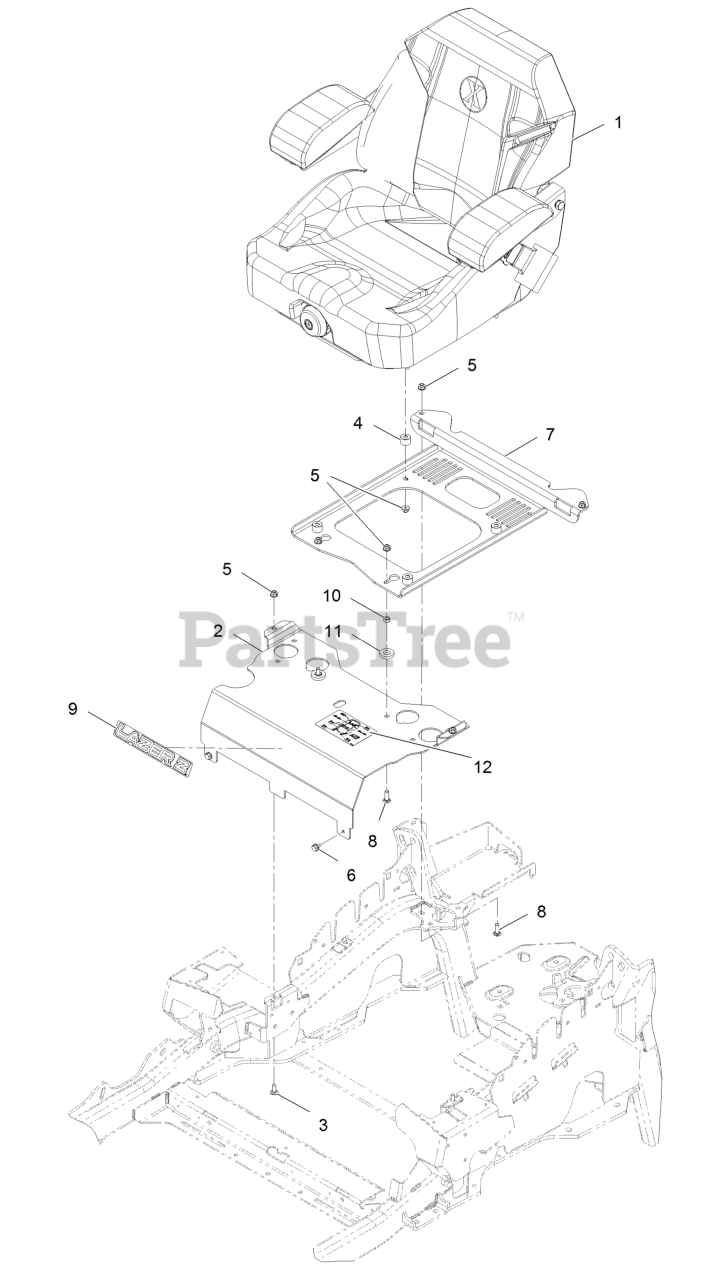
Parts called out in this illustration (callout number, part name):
1	KIT-SUSPENSION SEAT
2	Panel-Front, Seat Mount
3	SCREW-CARR
5	NUT-HF, NI
7	PLATE-SUPPORT, SEAT
8	SCREW-CARR
9	DECAL, LAZER MODEL
10	NUT-HEX
12	DECAL-SERVICE AID
